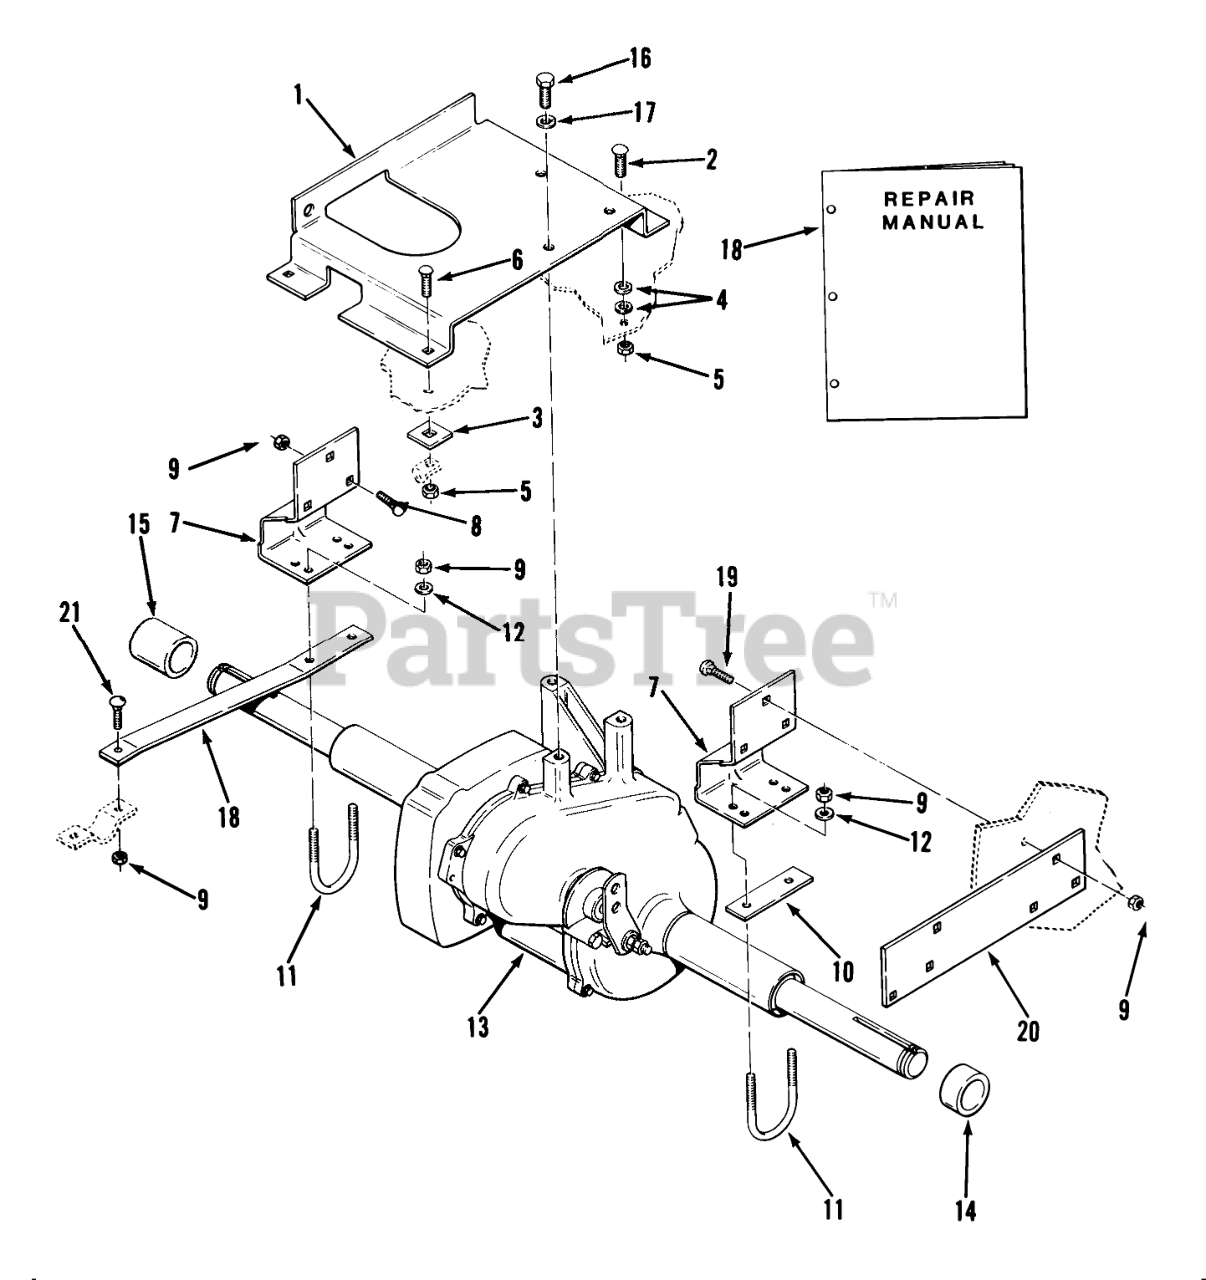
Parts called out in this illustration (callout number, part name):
1	Differential Support
2	Bolt-Carriage
3	PAD-SHORT R
4	WASHER 5/16 SAE
5	Nut
6	Bolt-Carriage
7	Bracket
8	CARRIAGE BOLT -4
9	Nut
10	Spacer
11	U-BOLT AXLE MTG
12	WASHER 5/16 SAE
13	Sleeve
14	SPACER-AXLE LH
15	Axle Spacer RH
16	BOLT
17	LOCKWASHER
18	BRACE FRAME
19	Bolt
20	Frame Brace LH
21	Bolt-Carriage
